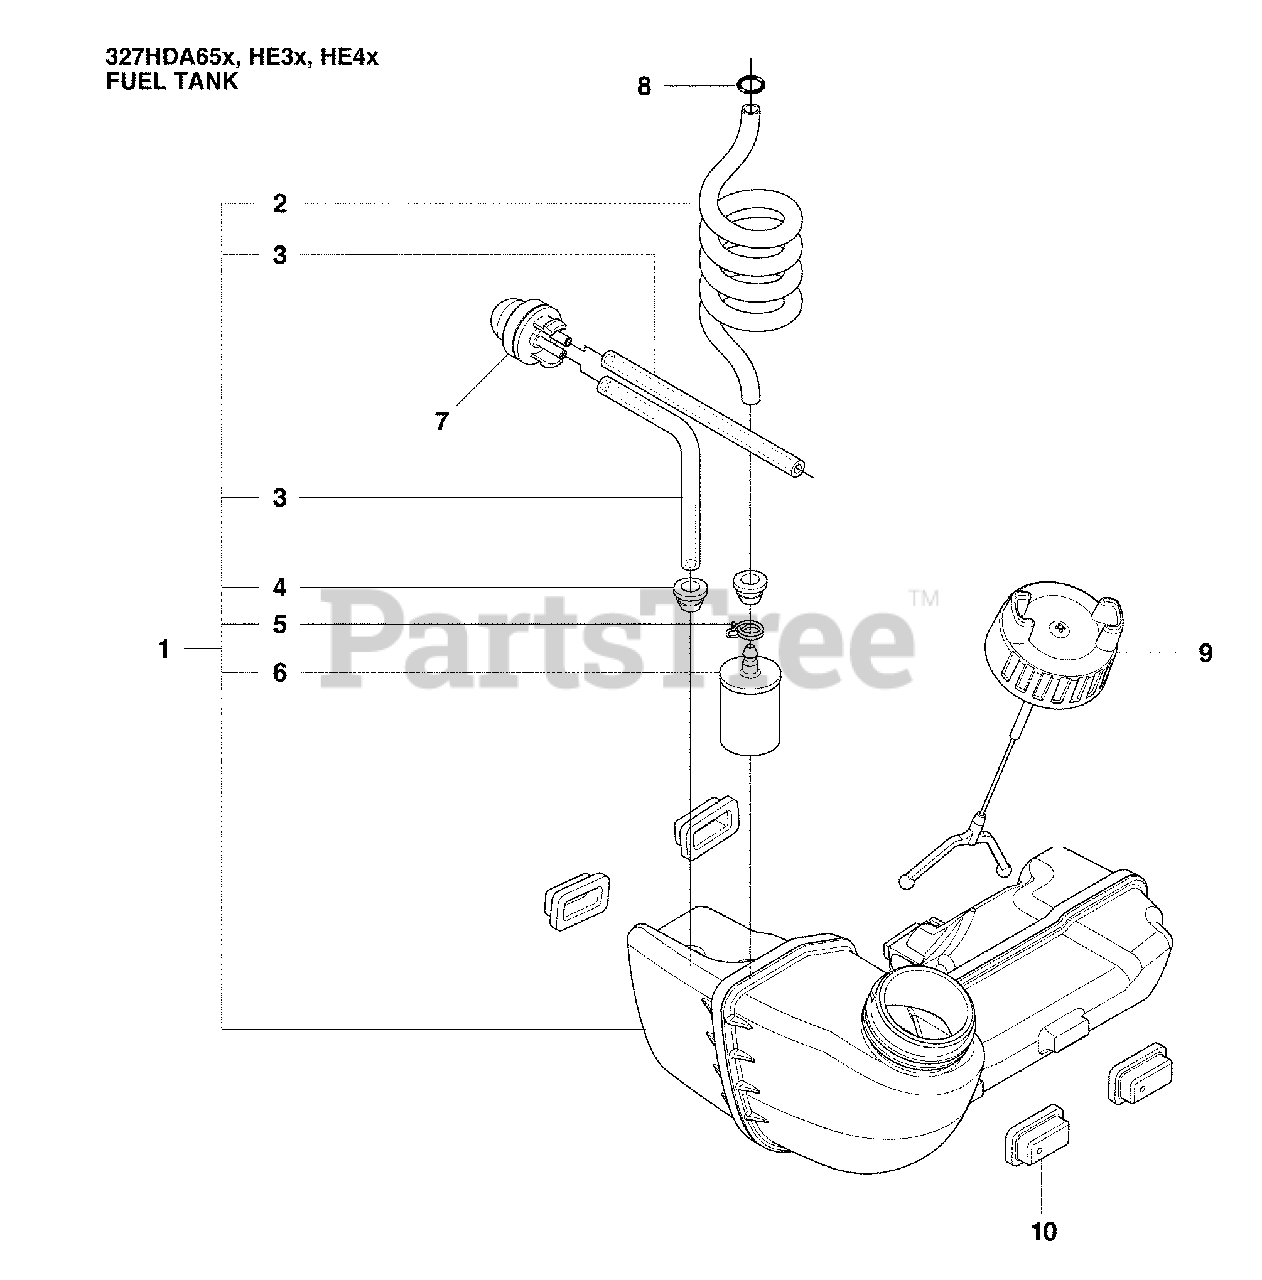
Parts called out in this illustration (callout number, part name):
1	Fuel Tank Assembly
2	Fuel Hose
3	Fuel Hose, Clear
4	Fuel Line Grommet
5	Hose Clamp
6	Fuel Filter Kit
7	Air Purge Bulb
9	Fuel Cap
